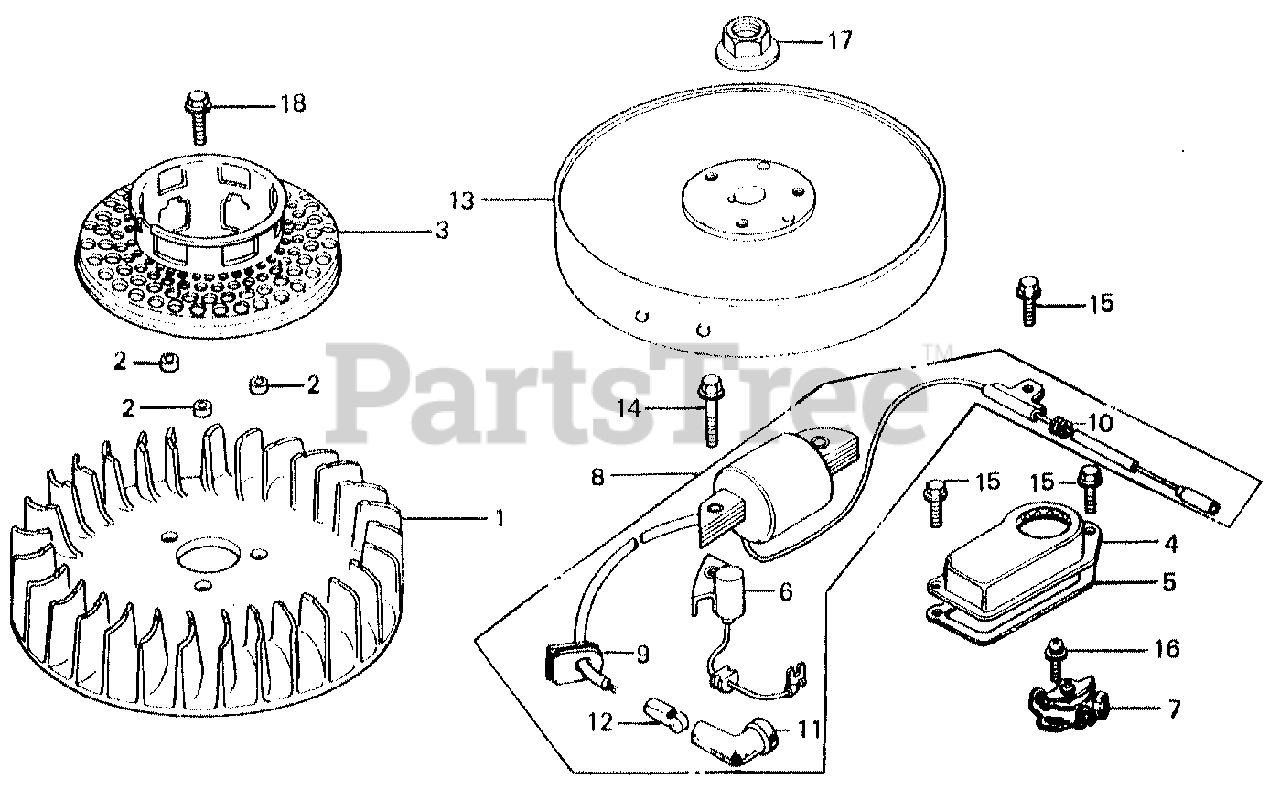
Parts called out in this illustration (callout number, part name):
1	FAN, COOLING
2	COLLAR, FAN
3	PULLEY, STARTER
4	COVER, POINTS
5	GASKET, POINT COVER
6	CONDENSER
7	POINTS ASSY.
8	COIL ASSY., IGNITION
8	COIL ASSY., IGNITION (NOT AVAILABLE)
9	GROMMET, WIRE
10	GROMMET, PRIMARY WIRE
11	CAP, IGNITION (SUMITOMO)
11	CAP, IGNITION (TOYO)
12	TERMINAL, PLUG
13	FLYWHEEL
14	BOLT, FLANGE (6X32)
15	BOLT, FLANGE (5X10)
16	SCREW-WASHER (5X12)
17	NUT, SPECIAL (14MM)
18	BOLT, FLANGE (6X16)
